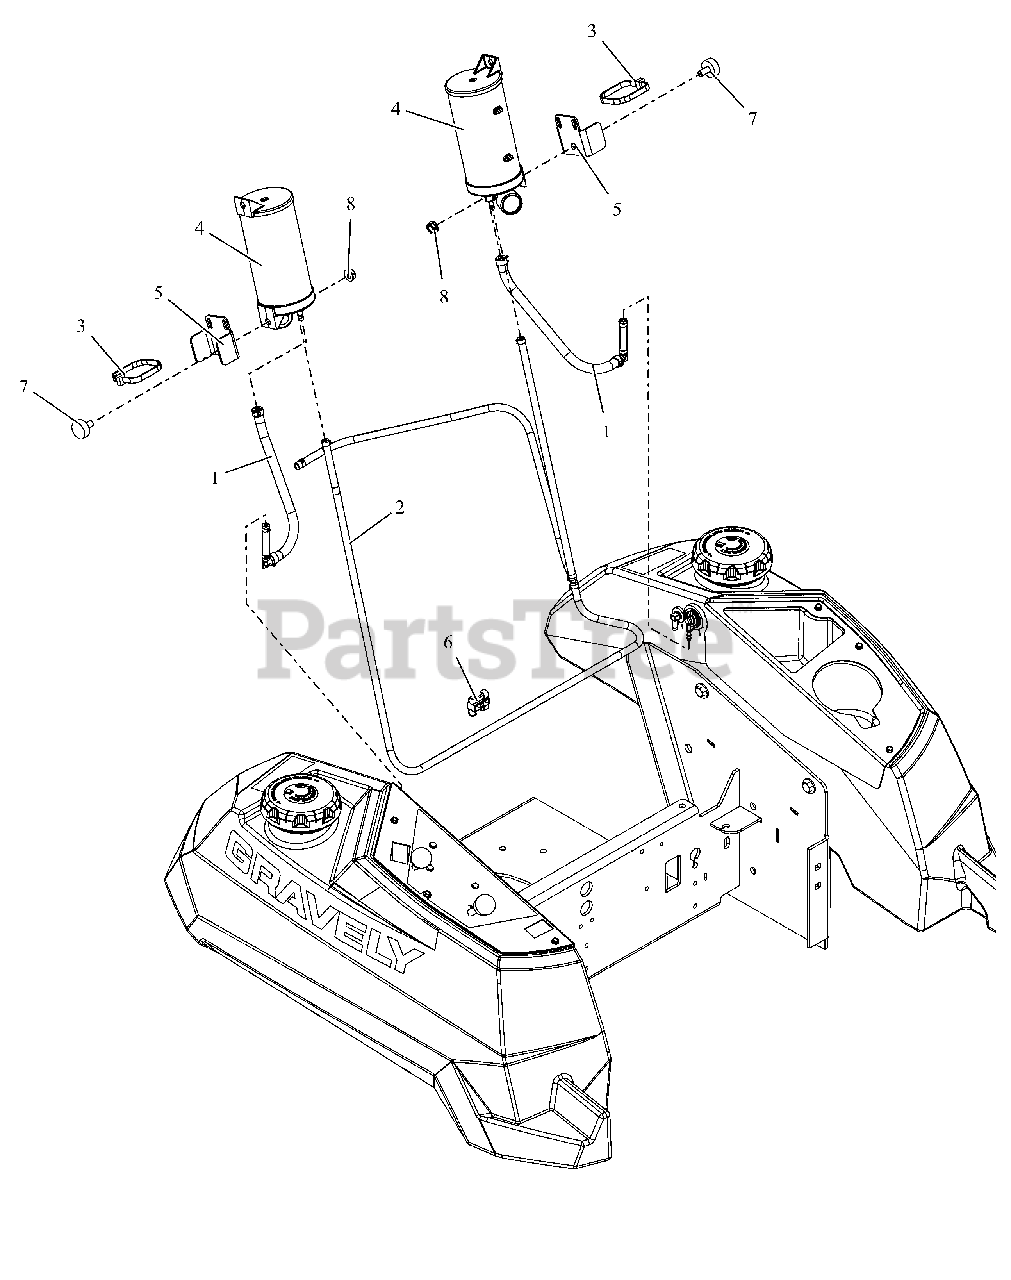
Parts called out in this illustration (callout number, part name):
1	ASM, CANISTER VENT LINE
2	ASM, VAPOR LINE (CARB)
3	TIE WRAP, 15.25" X 120 LBS
4	CANISTER, 400 CC CARB
5	CARB CANISTER MTG BRKT - BLACK
6	CLIP, T, .38-.50
7	BUMPER, RUBBER
8	@NUT-SPNLK-FLG .312-18 YWZC
